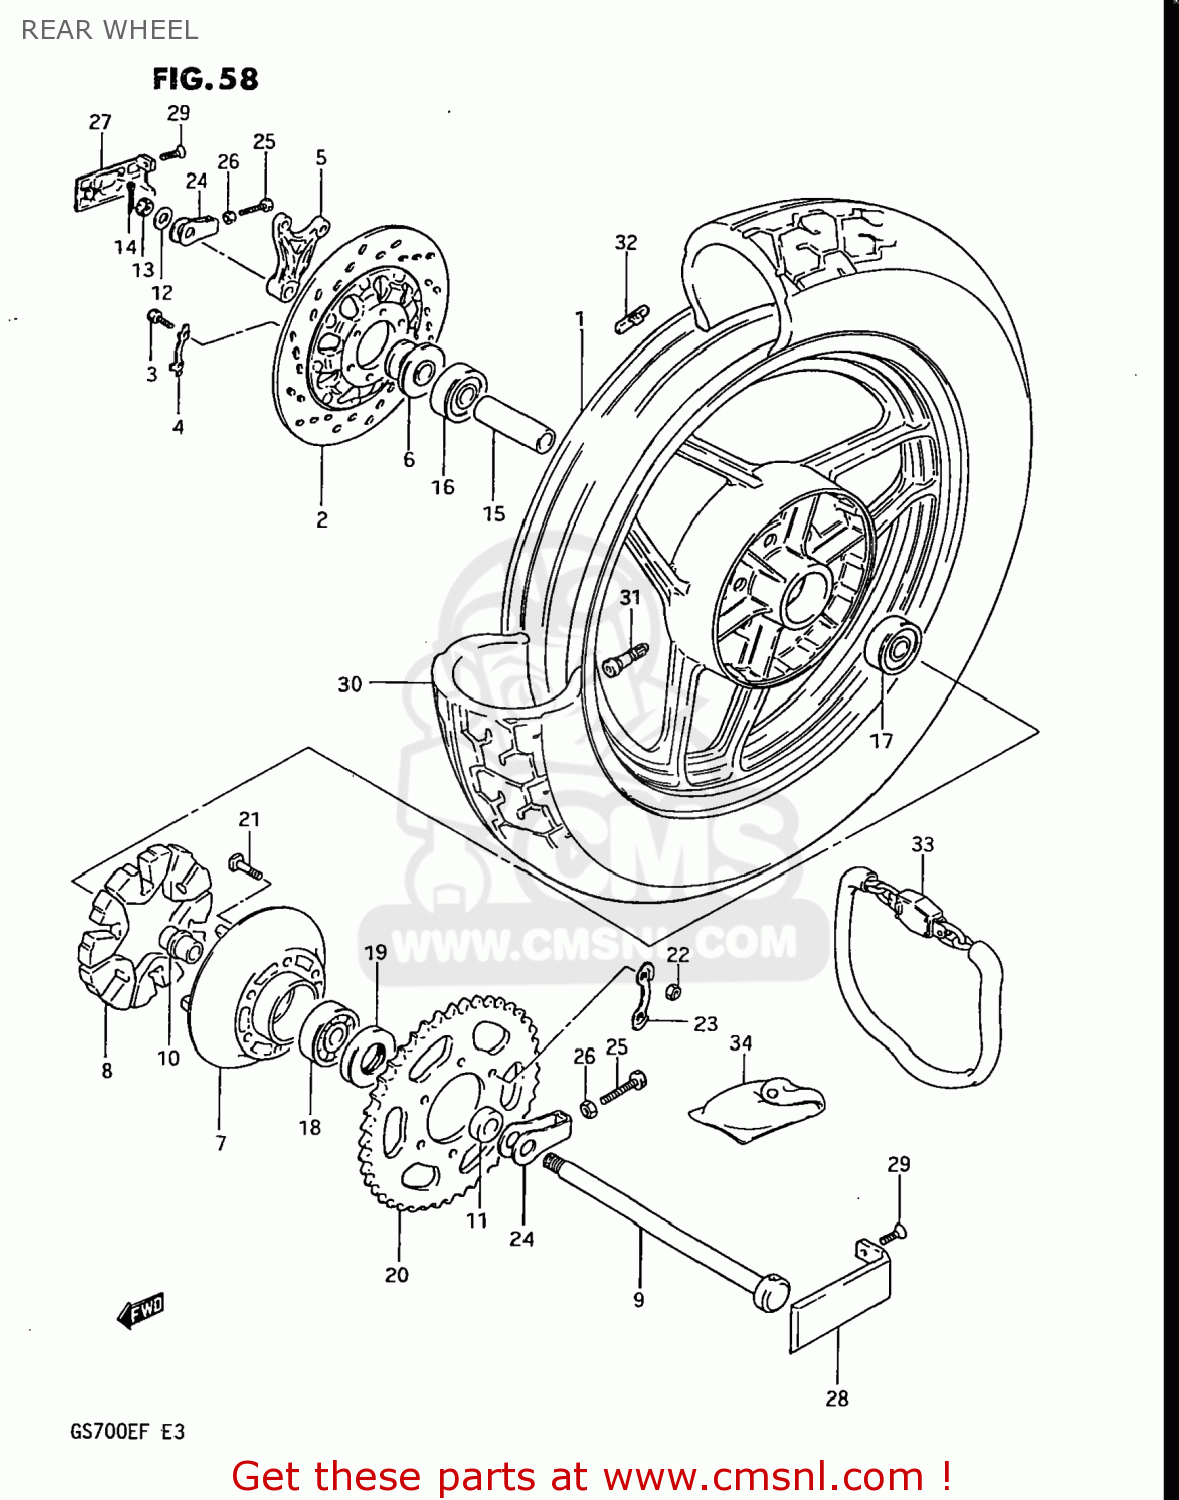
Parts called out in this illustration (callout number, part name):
1	CASTING WHEEL,REAR 2.50
2	DISC,BRAKE
3	BOLT(8X30)
4	WASHER
5	BRACKET,REAR CALIPER
6	SPACER,REAR AXLE
7	DRUM,REAR SPROCKET MOUNT
8	ABSORBER,REAR HUB SHOCK
9	AXLE,REAR
10	RETAINER,RR SPROCKET DRUM
11	SPACER(17X33X11.3)
12	WASHER
13	NUT
14	PIN,COTTER
15	SPACER(17.5X25X88)
16	BEARING
17	BEARING
18	BEARING
19	SEAL,OIL(33X62X7)
20	SPROCKET,REAR (NT:45)
21	BOLT(10X35.5)
22	NUT
23	WASHER
24	ADJUSTER,CHAIN
25	BOLT 8X50
26	NUT
27	COVER,CHAIN ADJUSTER,R
28	COVER,REAR AXLE,LEFT
29	SCREW 5X16
30	TIRE
31	VALVE,TIRE
32	BALANCER,WHEEL
33	CHAIN LOCK ASSY
34	BAG,CHAIN LOCK
